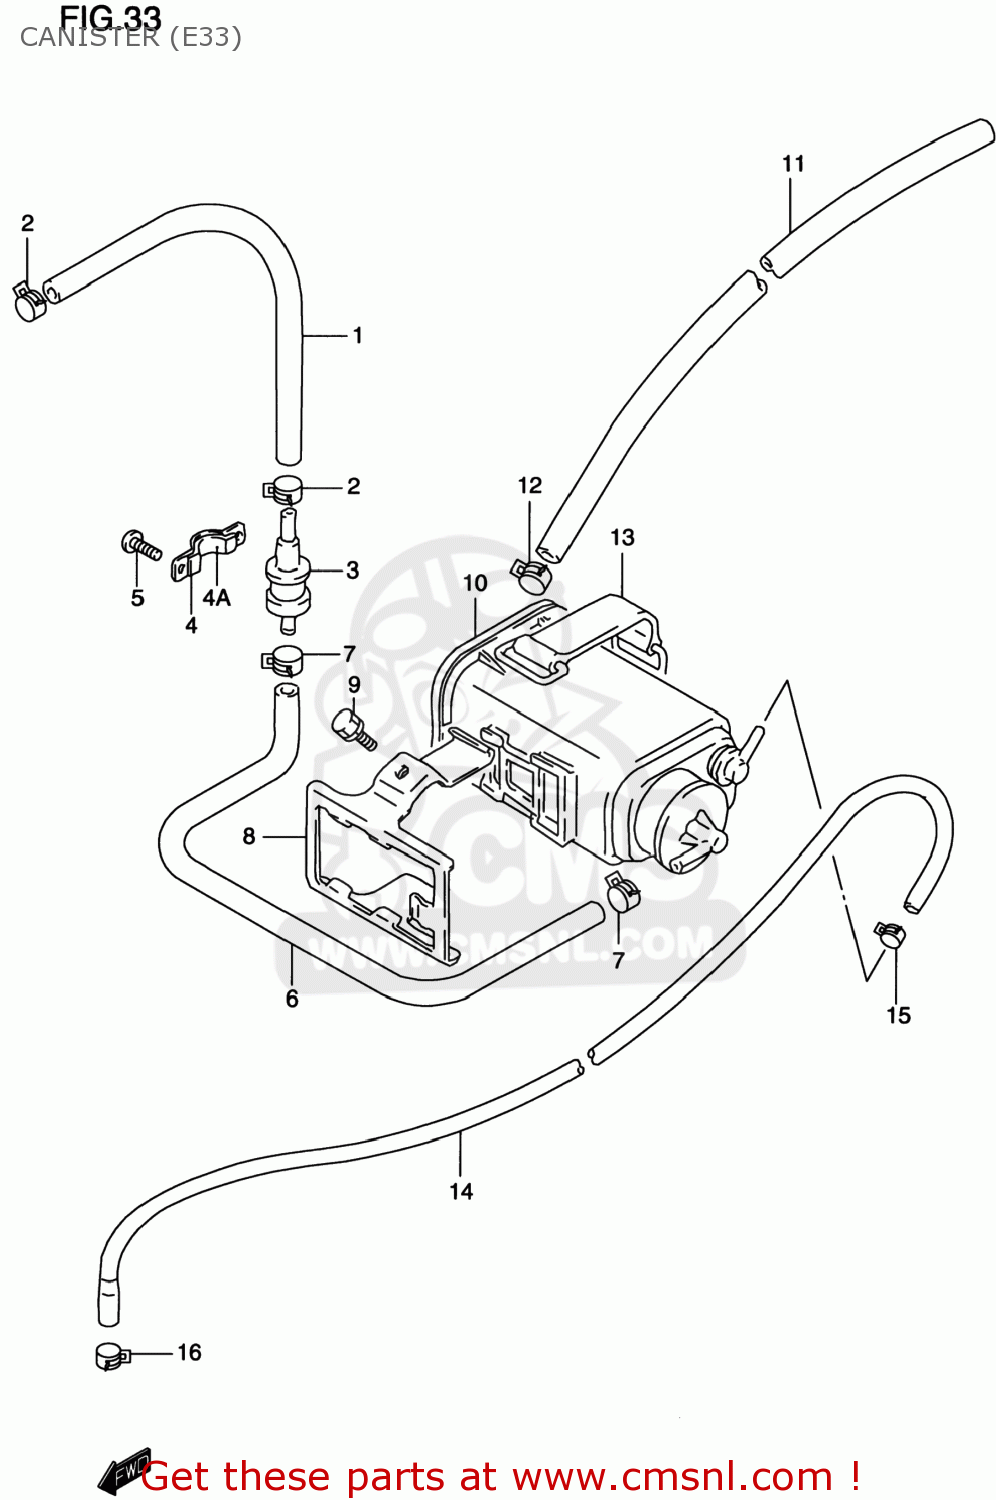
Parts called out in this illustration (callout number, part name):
1	HOSE(5.4X11.4X600)
2	CLIP
3	VALVE,FUEL TANK BREATHER
4	PLATE,FUEL TANK BREATHER NO.2
4A	CUSHION
5	SCREW
6	HOSE(5.4X11.4X350)
7	CLIP
8	PLATE,CSTR FITING
9	BOLT
10	CANISTER ASSY,CHARCOAL
11	HOSE(7X12X600)
12	CLIP
13	BAND
14	HOSE(3.5X7.5X600)
15	CLIP
16	CLIP
